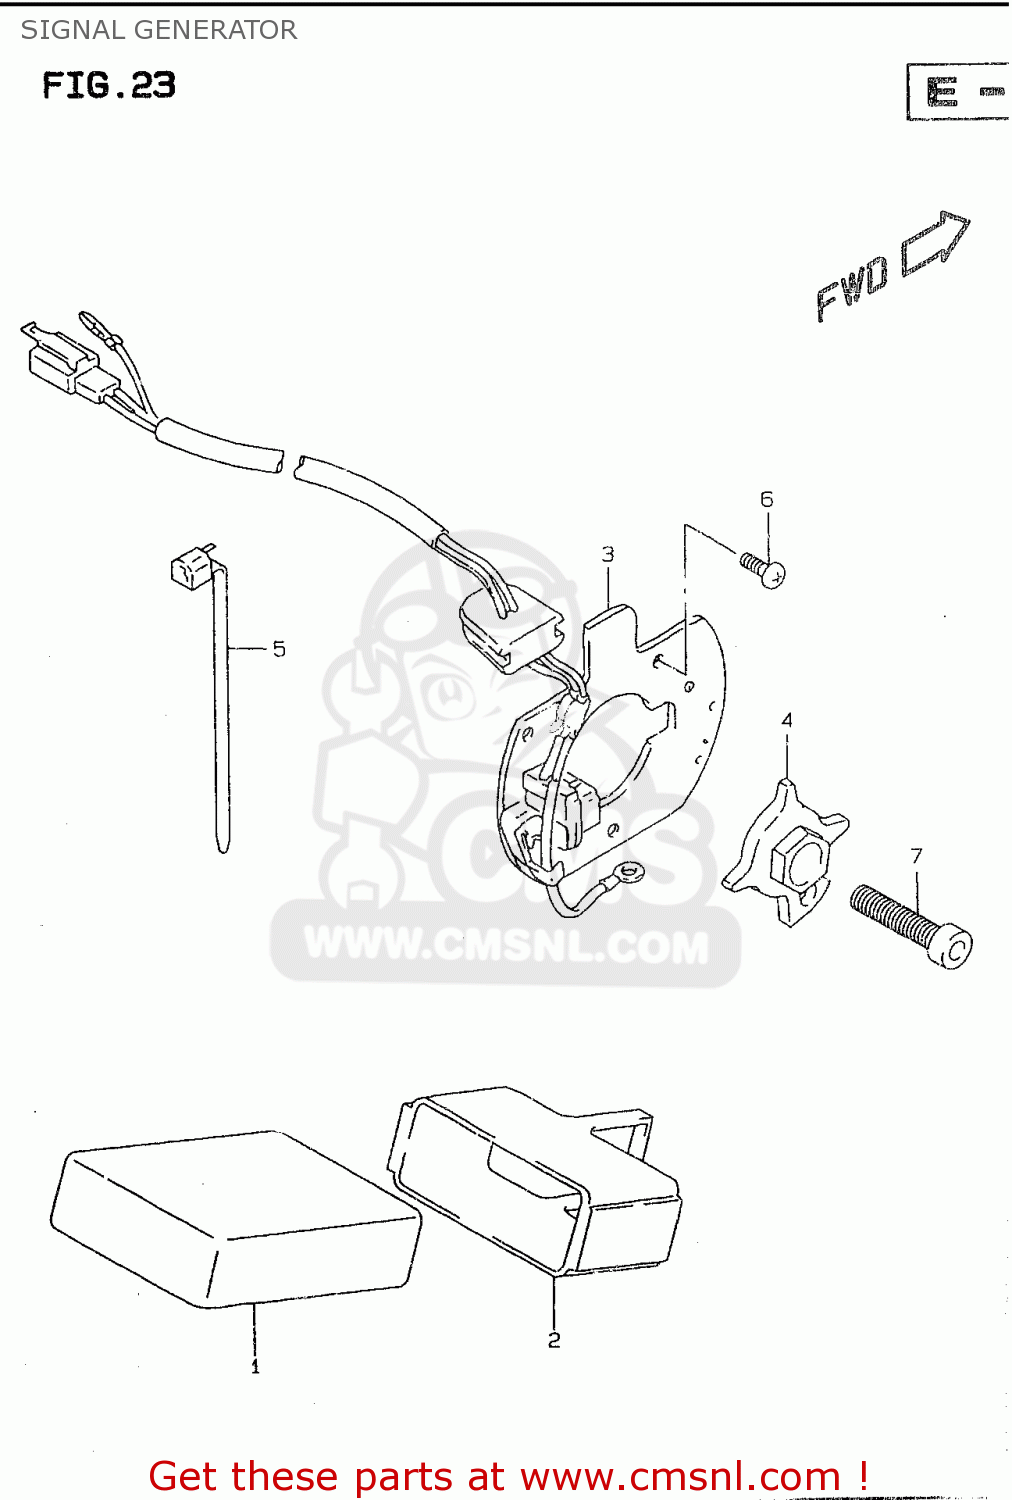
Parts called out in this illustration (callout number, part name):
1	IGNITOR ASSY
2	CUSHION,IGNITOR
3	GENERATOR ASSY,SIGNAL
4	ROTOR,SIGNAL GENERATOR
5	CLAMP(L:95)
6	SCREW
7	BOLT
